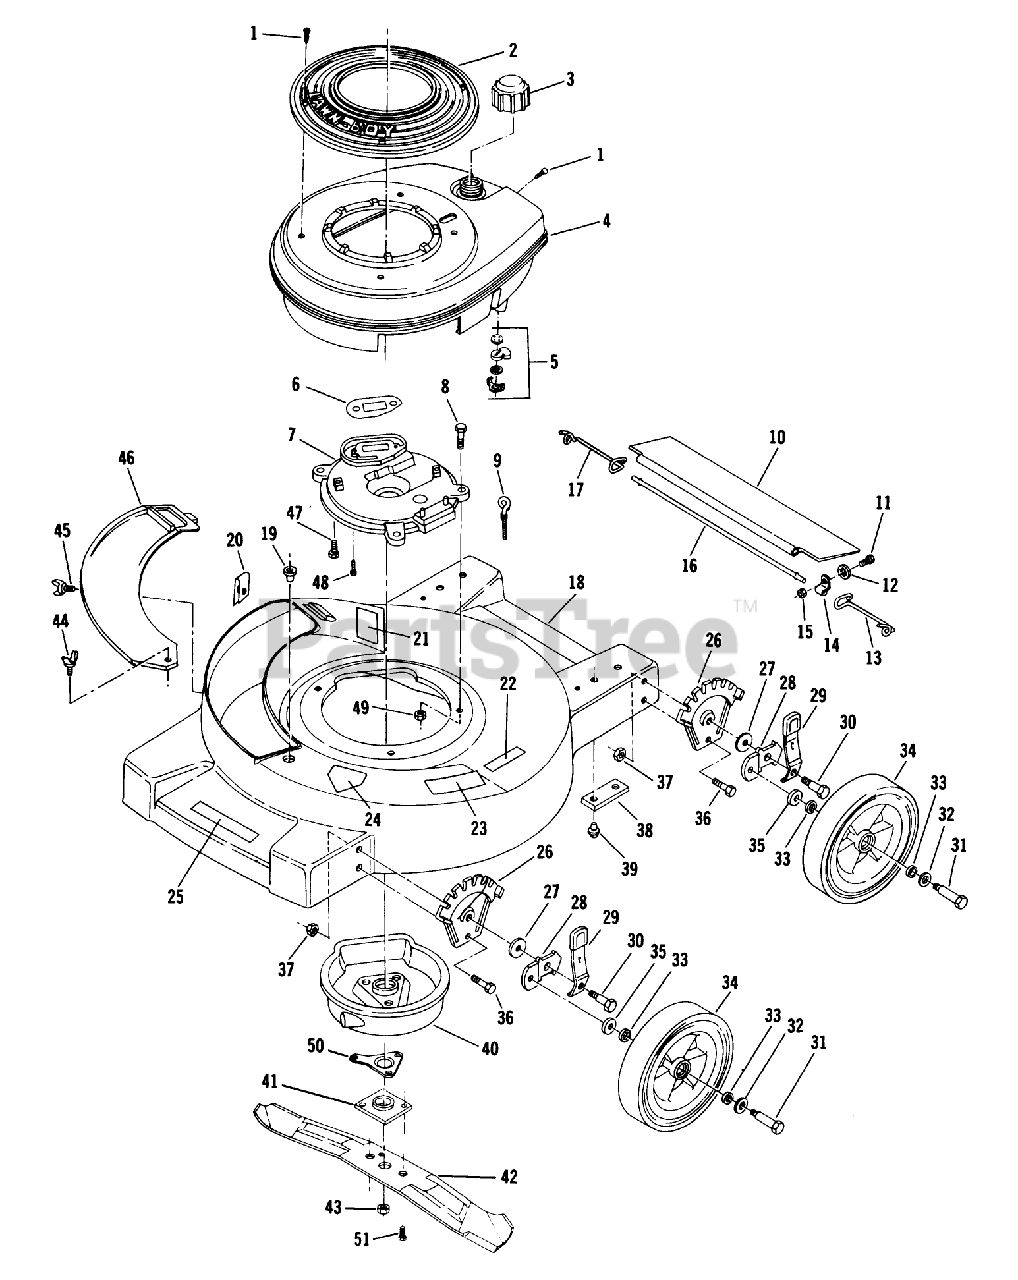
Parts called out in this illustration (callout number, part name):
1	SCREW - SELF TAPPING
3	FUEL CAP & INSERT
5	SHUT OFF VALVE KIT
7	PLATE,MUFFLER F
8	SCREW
9	EYE BOLT WAS MFG
10	SHIELD
12	WASHER F
13	SPRIG T/SHLD ASOC
14	CLAMP ROD KMC
15	LOCKNUT E
16	ROD 21" ADVANCE
17	SPRING;TRAILING SHIELD RH
23	PAD FOOT
27	WASHER
31	BOLT WHEEL
32	SPACER
33	WASHER
35	WASHER WROUGHT
37	LOCKNUT
39	SCREW
41	PLATE AND COLLAR ASM
43	NUT-BLADE
44	WING SCREW LAWRE
46	PLATE
48	SCREW V
49	NUT-LOCK F
50	SUPPORT F
51	SCREW
